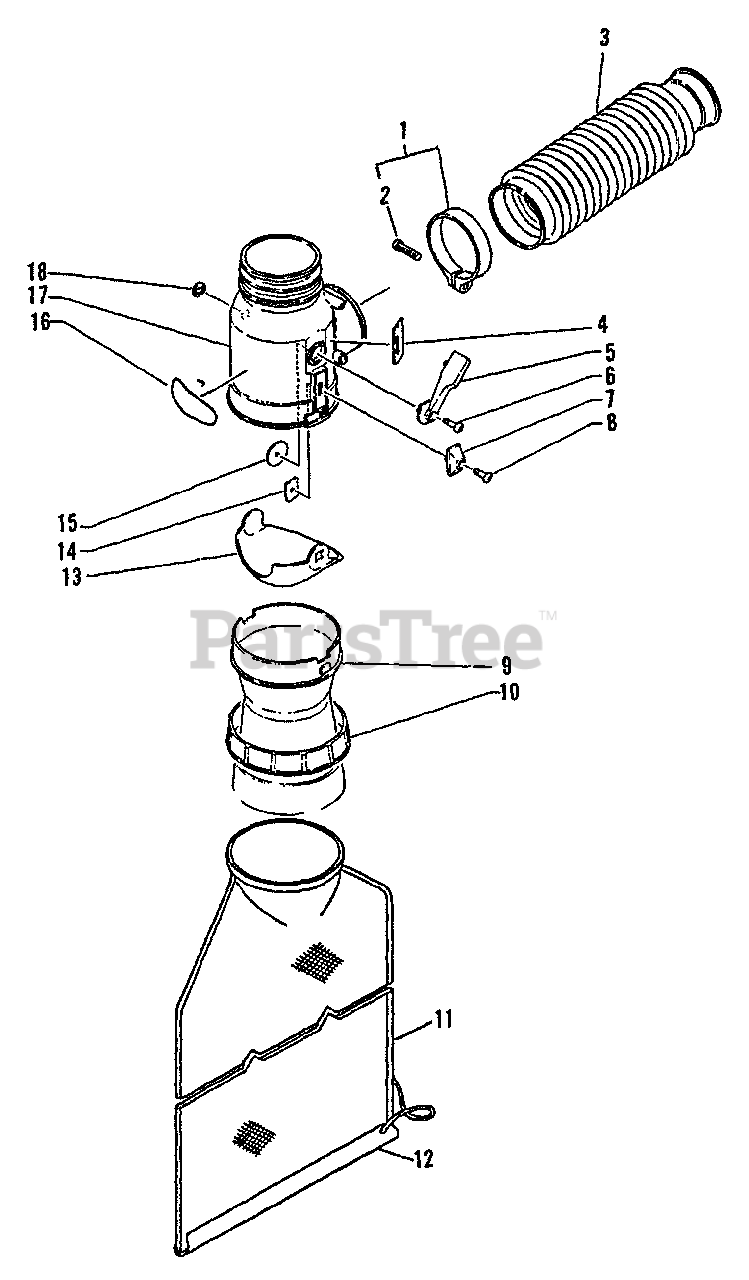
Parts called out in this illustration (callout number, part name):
1	CLAMP KIT
2	SCREW - 5X25
3	TUBE, BLOWER - FLEXIBLE
4	LABEL - FUNCTION
6	SCREW - 5X14
8	SCREW - 4X14
9	CONNECTOR
11	BAG, DEBRIS
12	CLIP, VACUUM BAG
16	LABEL - ECHO
17	TUBE, SUCTION
18	RING, RETAINING - 8
